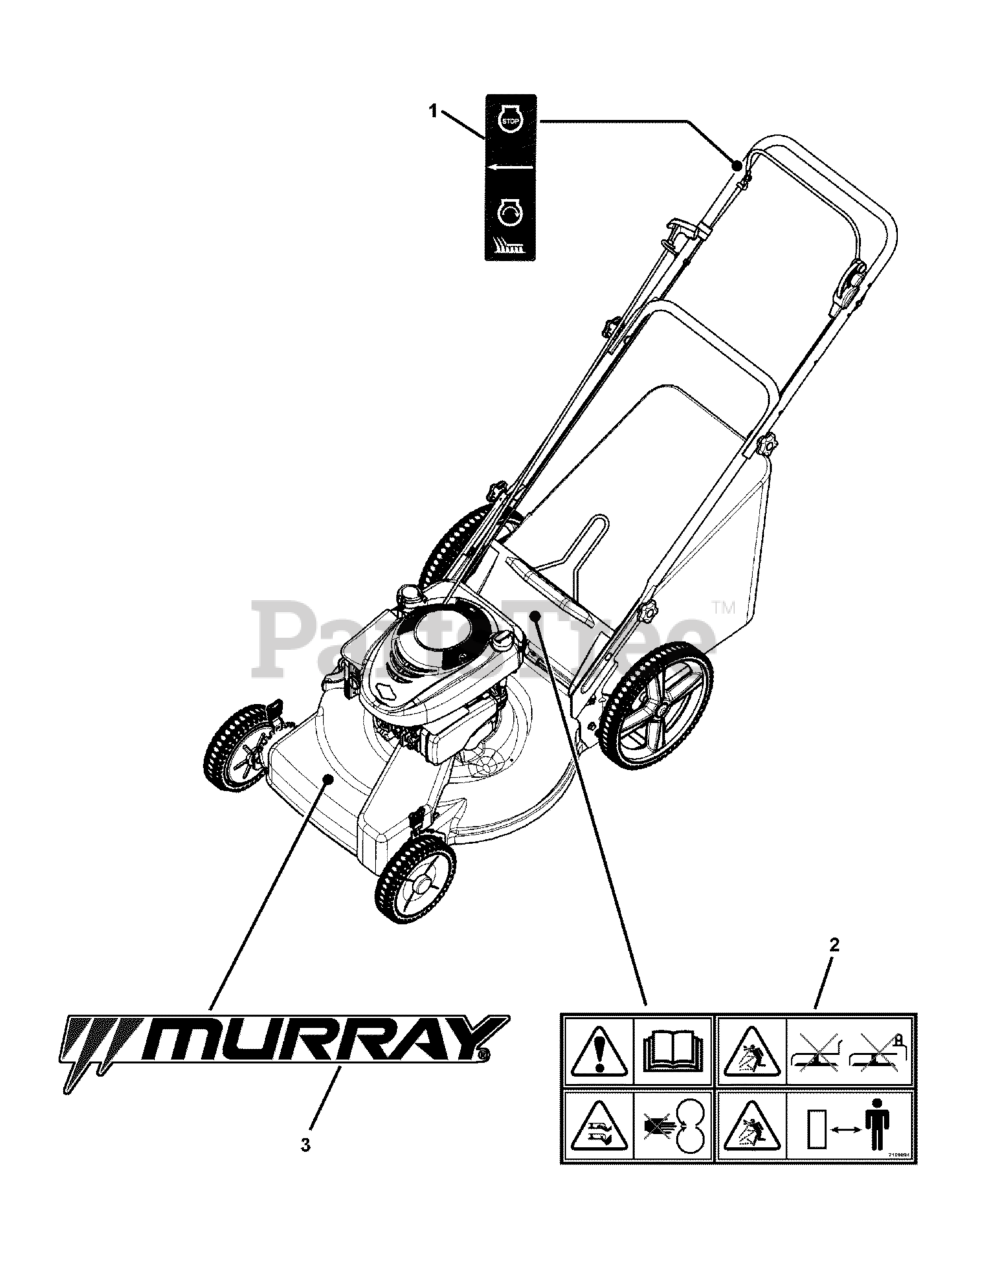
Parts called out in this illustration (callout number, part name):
1	DECAL, OPC Bail International Symbol
2	DECAL, Warning, Euro, Multi-Panel
3	DECAL, Murray Logo, Deck, 20FC
